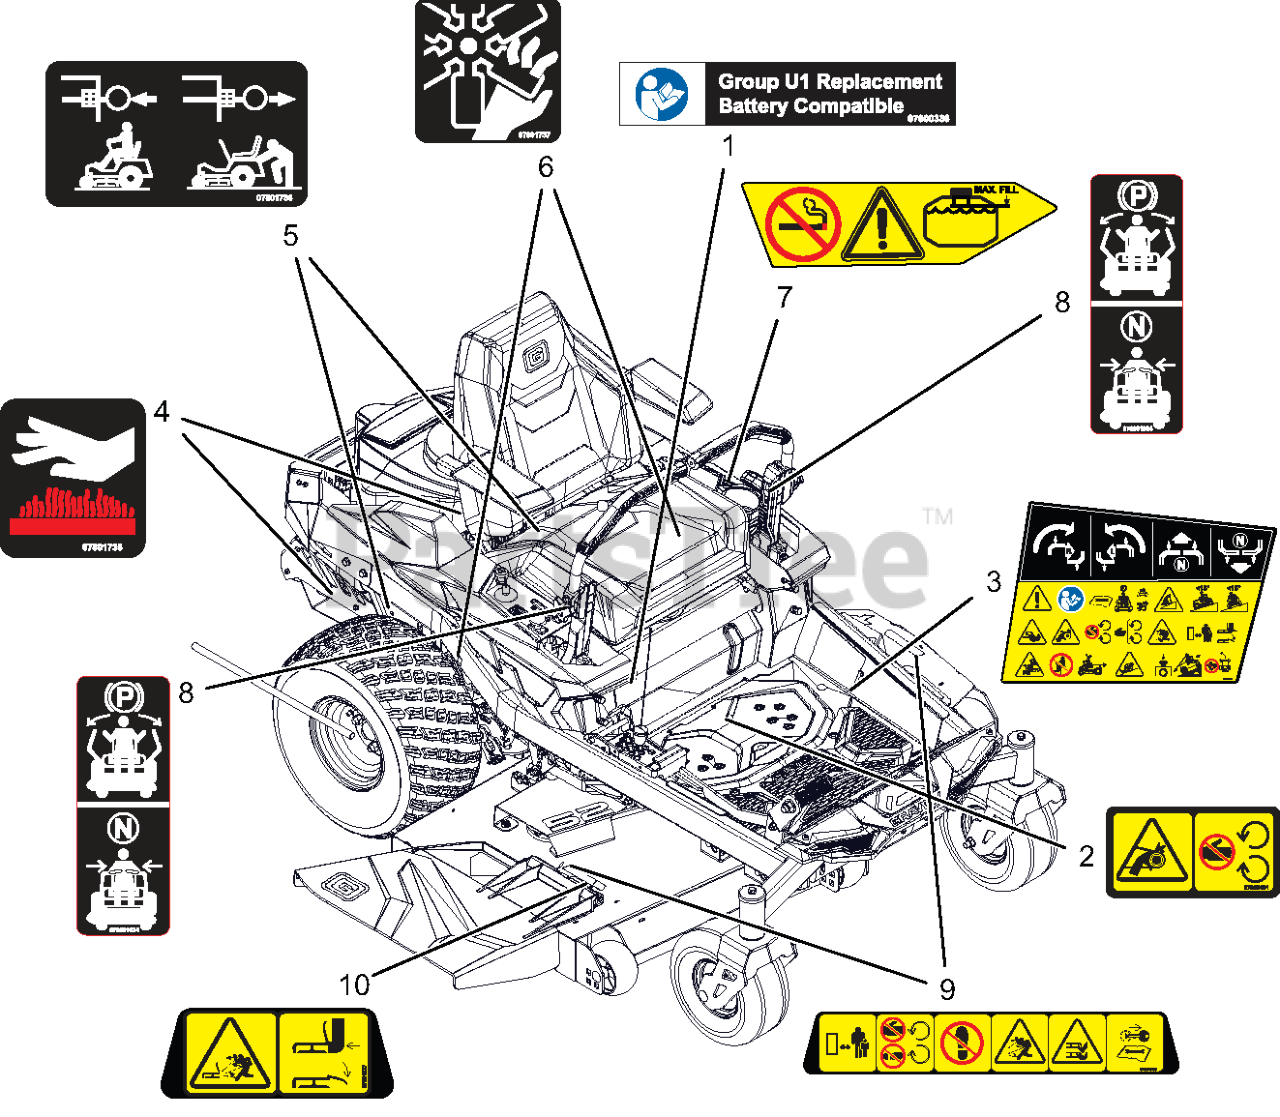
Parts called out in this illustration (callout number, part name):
1	DECAL, U1 BATTERY REPLACEMENT
2	DECAL, SAFETY - GUARDING
3	DECAL- MAIN SAFETY-INSTRUCTION
4	DECAL,SAFETY HOT SURFACE
5	DECAL,TRANSAXLE DISCONNECT
6	DECAL, DANGER FAN
7	DECAL, FUEL WARNING
8	DECAL- STEERING-BRAKE
9	DECAL- SAFETY - MOWER DECK
10	DECAL- SAFETY - DECK GUARDING
